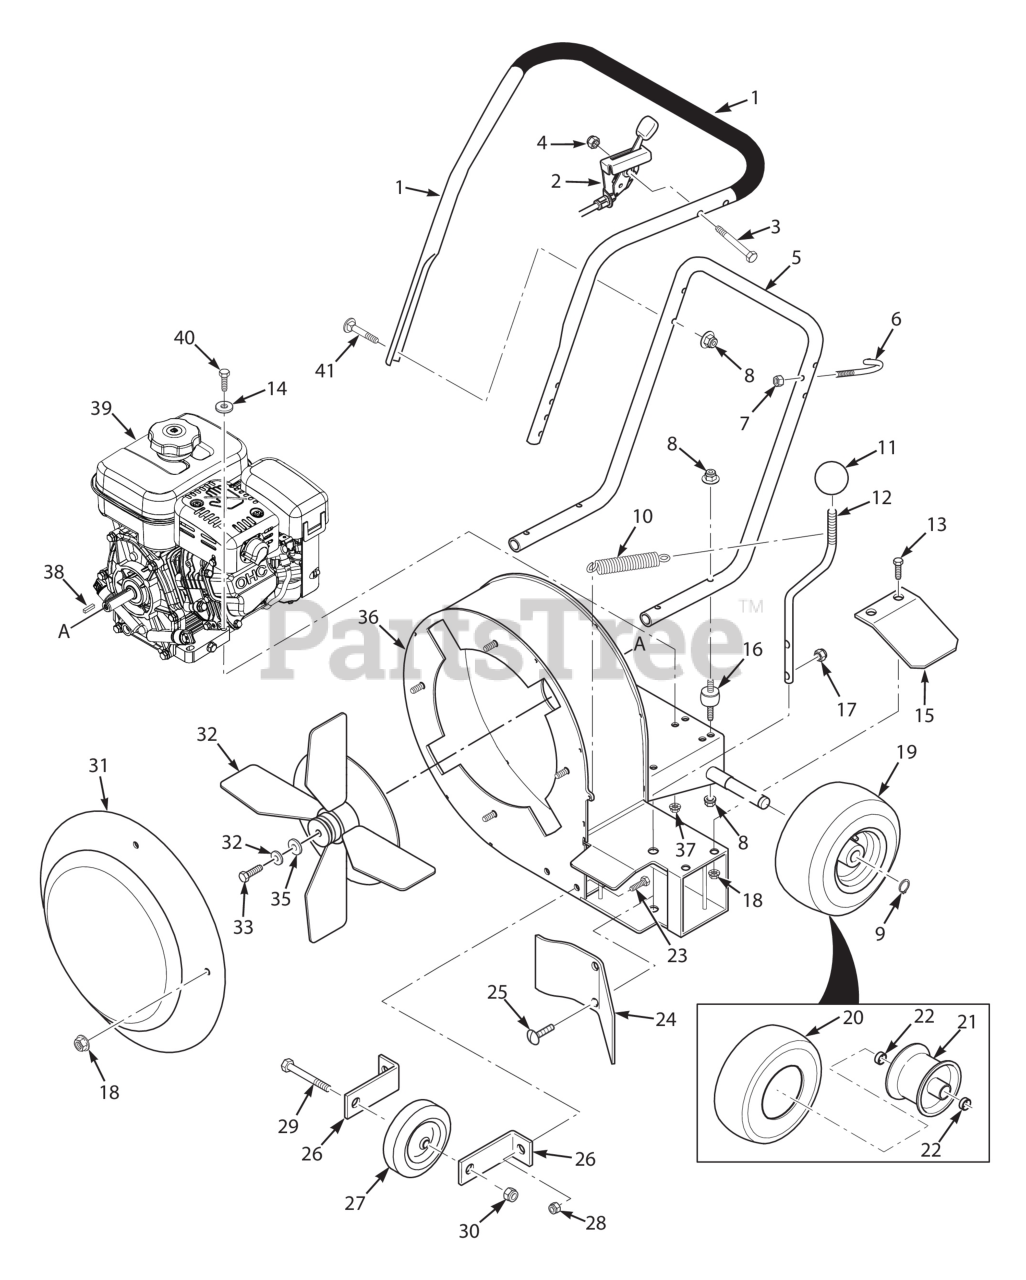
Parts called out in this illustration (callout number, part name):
1	Handle, Upper w / Grip - LBC
2	Cable, Throttle Control
3	Bolt, 1/4-20 x 2-1/2"
4	HEX, NUT, ELASTIC STOP LOCK, 1/4-20
5	Handle, Lower Folding - LBC
6	Guide, Pull Rope
7	NUT, 1/4-20 SERRATED FLANGE HEX HEAD
8	Nut, Flange Head Elastic Stop 5/16-18
9	RETAINING RING, 5/8 EXT. - BASIC
10	Spring, Air Discharge Door
11	Knob, 3/8-16 Thread
12	Rod, Air Control
13	Capscrew, 5/16-18 x .75 Serrated Flange Hex Head
14	Flatwasher, 5/16-.375 x .875 x .083 (35BV & 37BV-EFI)
15	Deflector, Side Air
16	Mount, Vibration
17	NUT, 1/4-20 SERRATED FLANGE HEX HEAD
18	Nut, Serrated Flange 5/16-18 (Right Front Engine Mounting, Briggs and Kohler Only)
19	Wheel Assembly, 4.10 x 3.5-6
21	Rim w/Valve
22	Bearing
23	BOLT, SERRATED FLANGE HEX HEAD 5/16-18 X 3/4"
24	Door, Forward Air Control
25	Serr. Fl. Hex Head CPSCR, 1/4-20 x 3/4"
26	Bracket, Caster
27	Wheel
28	Nut, Flange Head Elastic Stop 5/16-18
29	Capscrew, Hex Head 3/8-16 x 2-1/2"
30	HEX NUT, ELASTIC STOP LOCK, 3/8-16
31	Baffle Weldment, Intake w / Decal
32	Impeller Weldment, LBC 15 x 3/4" Bore
33	Bolt, Hex Head 5/16-24 x 2" w / Patch
34	Lockwasher, 3/8" Spring, Kawasaki FX / FS
35	Flatwasher, 3/8-.406 x 1-1-1/2 x 7 Gauge
36	Blower Housing Weldment w / Decals - LBC
37	Nut, Flange Head Elastic Stop 5/16-18
38	KEY, 3/16 X 3/16 X 1-1/2
39	Engine, Briggs & Stratton BS950 (not available through Scag Power Equipment)
40	Bolt, Hex Head 5/16-18 x 1-1/2" (Right Front Engine Mounting, Briggs and Kohler Only)
41	CARR BOLT, 5/16-18 X 1.75
